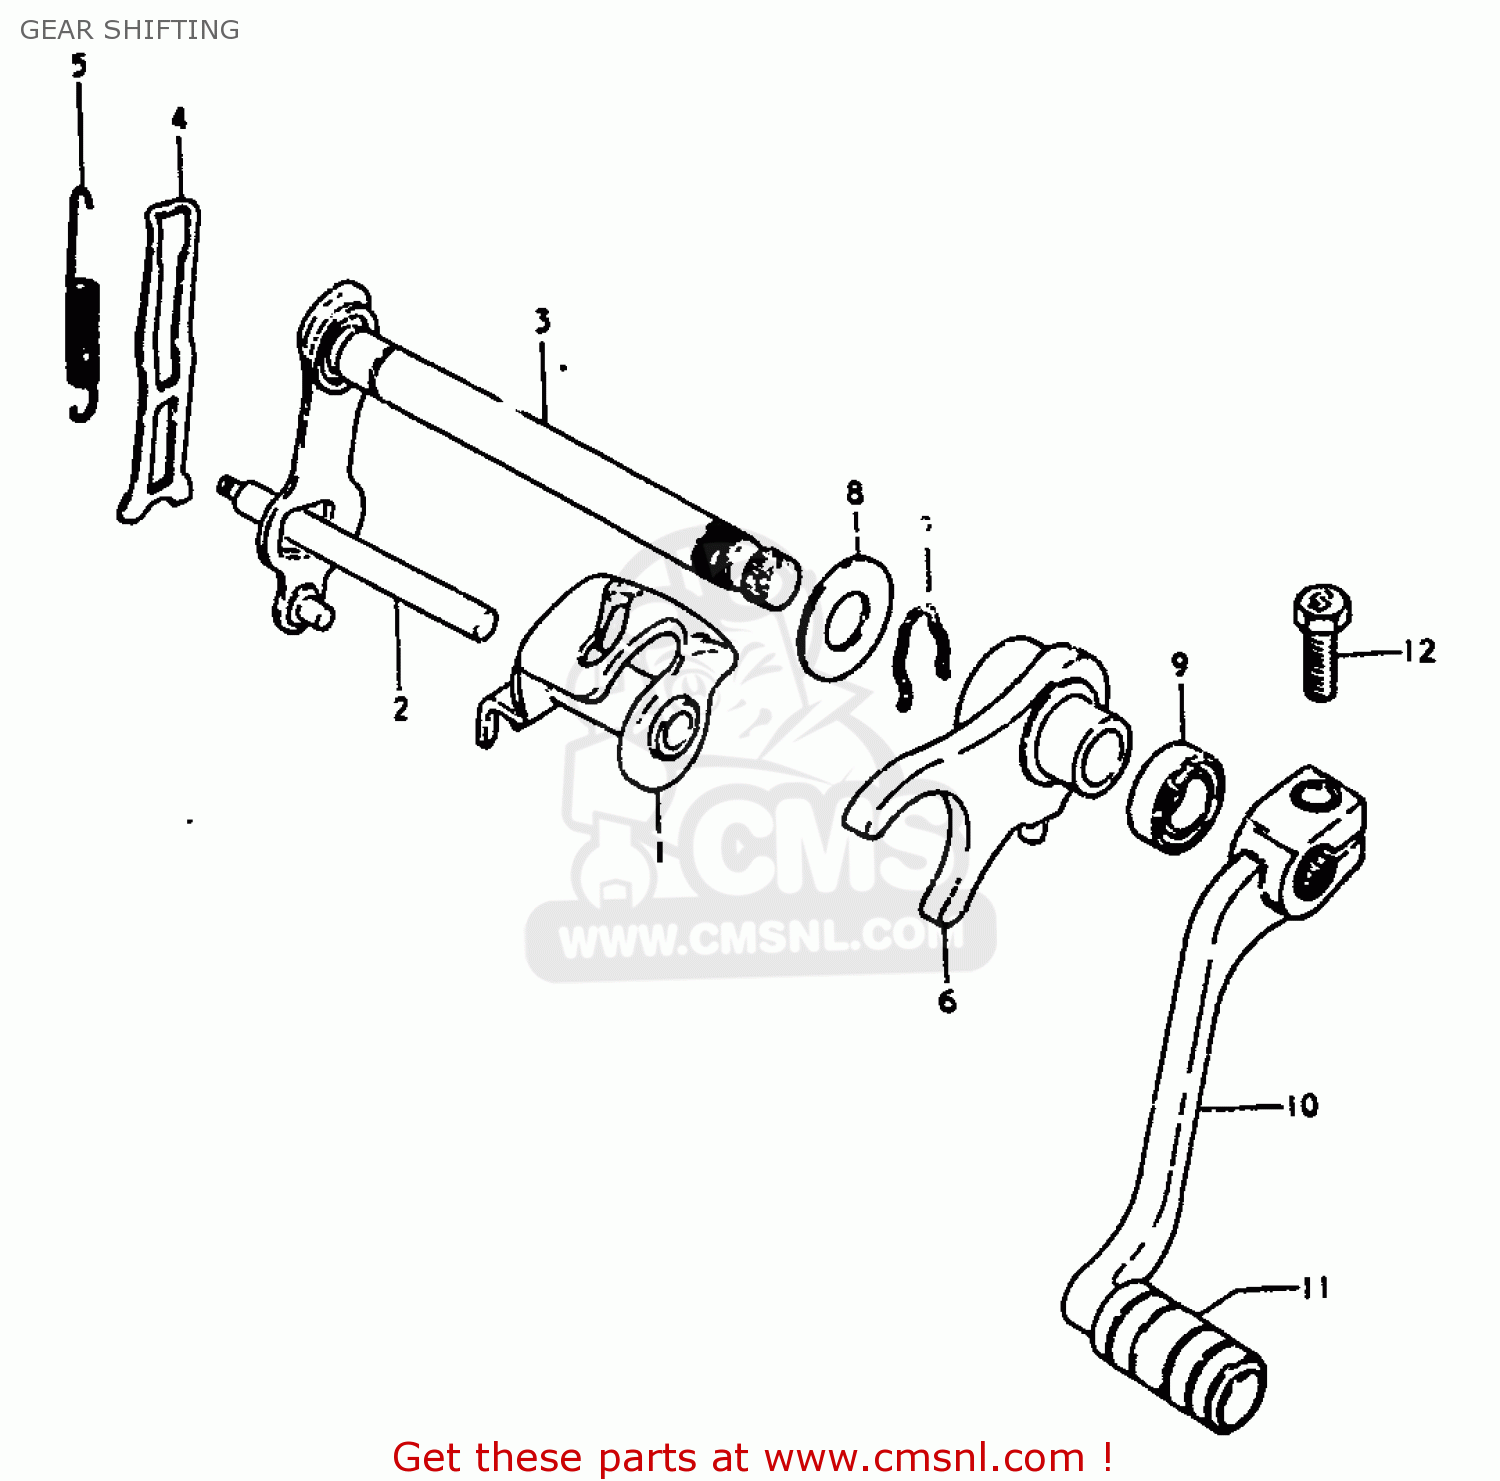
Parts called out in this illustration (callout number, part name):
1	CAM,GEAR SHIFT
2	SHAFT,GEAR SHIFT CAM
3	SHAFT,GEAR SHIFT
4	ARM,GEAR SHIFT CAM STOPPER
5	SPRING
6	FORK,GEAR SHIFT NO.1
7	SPRING,RETAINER
8	WASHER
9	OIL SEAL
10	LEVER ASSY,GEAR SHIFT
11	RUBBER,GEAR SHIFT PEDAL
12	BOLT
